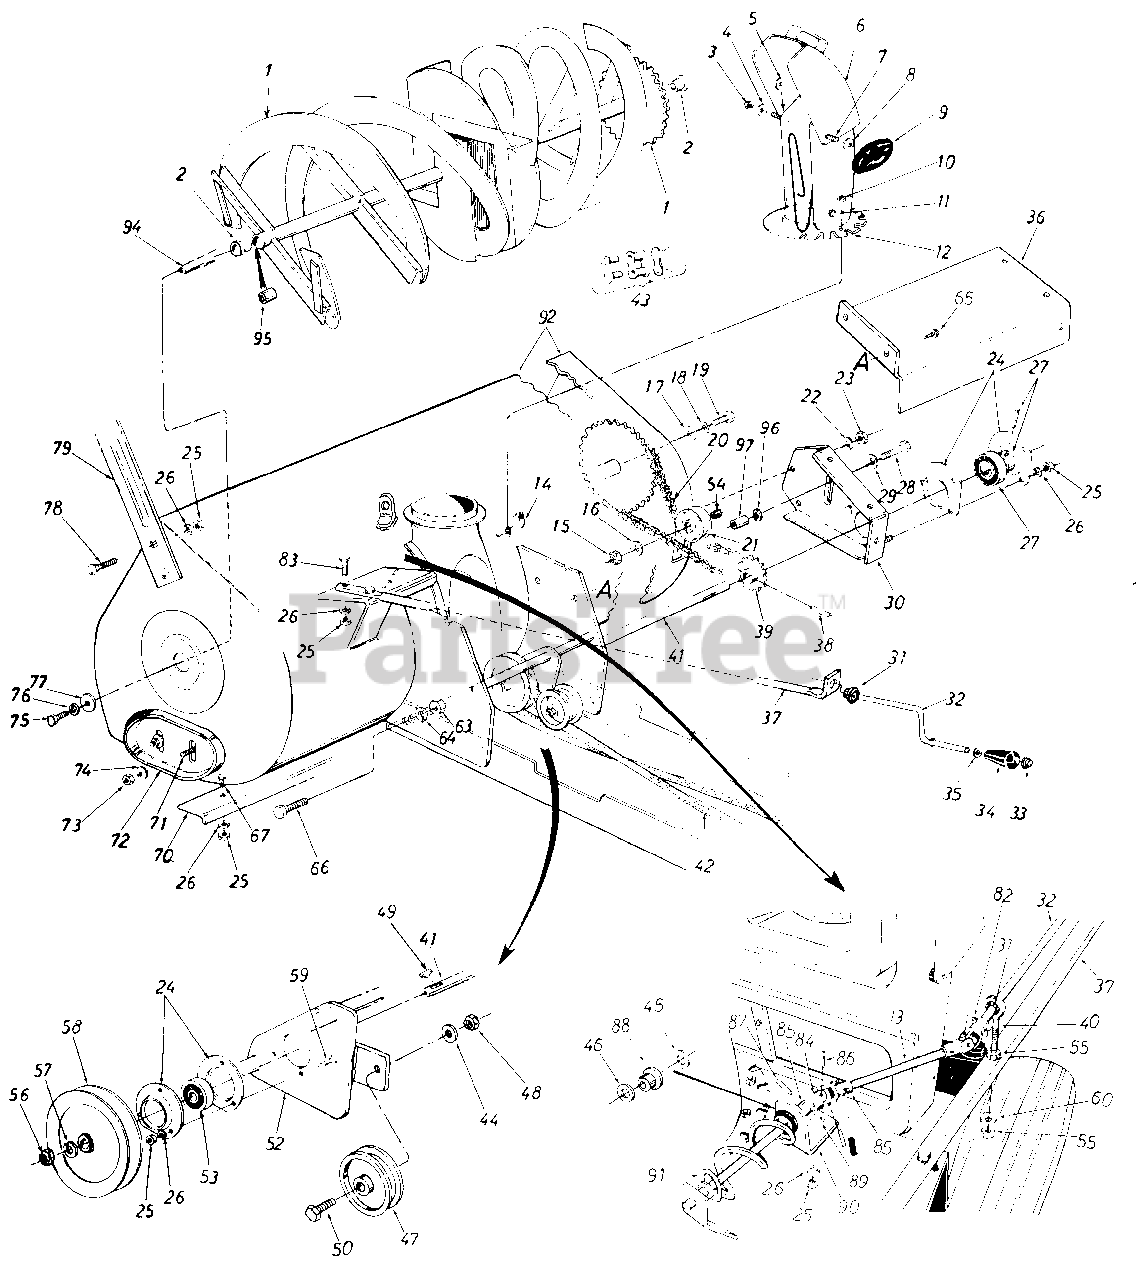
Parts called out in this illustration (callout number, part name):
1	Spiral Ass'y.
2	Flange Bearing
3	Hex Cent. L.-Nut 5/16-18 Thd.
4	Belleville Wash. 3/8" I.D.
5	Flat Washer 3/8" I.D.
6	Top Chute Ass'y.
7	Carriage Bolt 5/16-18 x .62" Lg.*
8	Belleville Wash. 3/8" I.D.
9	Hand Knob
10	Hex Cent. L.-Nut 1/4-20 Thd.
11	Push Cap .188" Dia. Rod
12	Chute Ass'y.
13	Chute Crank Extension Rod
14	Chute Flange Keeper Ass'y.
15	L.-Nut 3/8-16 Thd
16	FI .-Wash.
17	Fl.- Wash.
18	Belleville Wash.
19	Hex Bolt 1/2-13 x 1.00" Lg.*
20	#420 Chain 1/2" Pitch x 77 Links
21	Plastic Idler 2.00" O.D.
22	L.-Wash. 1/4" I.D.*
23	Hex Nut 1/4-20 Thd.*
24	Bearing Housing
25	Hex Nut 5/16-18 Thd.*
26	L.-Wash. 5/16" I.D.*
27	Self-Aligning Bearing
28	Hex Bolt 3/8-16 x 1.75" Lg. t
29	Belleville Wash. 3/8" I.D.
30	Chain Guard Ass'y.
31	Nylon Bushing
32	Chute Crank .375 Dia. x 33" Lg.
33	Push Nut 3/8" Rod
34	Knob 3/8" Dia. Hole
35	Flat Washer
36	Drive Shaft Cover
39	14 Teeth Sprocket Ass'y.
40	Eyebolt 5/16-18 x 3 .0 " Lg.
41	Drive Shaft
42	"V"-Belt 1/2" x 88" Lg. [ (Kevlar)
43	Master Link for #420 Chain
44	L.-Wash. 3/8" I.D.*
45	Fl.-Wash. .385 I.D. x .62" O.D.
46	Fl.-Wash. .390 I.D. x 1.50" O.D.
47	Fl.-Idler with Flanges
48	Hex Jam L.-Nut 3/8-26 Thd.
49	#61 Hi-Pro Key
50	Hex Bolt 3/8-16 x 1.50" Lg.*
52	Spiral Housing Ass'y.
53	Self-Aligning Bearing
54	Sleeve Bearing .50" I.D.
55	Hex Nut 5/16-18 Thd.*
56	Hex Nut 3/4-10 Thd.
57	L.-Wash. 3/4" I.D.
58	"V"-Pulley .750" I.D. x 6.00" O.D.
59	Hex Sems Bolt 5/16-18 x .75" Lg.*
60	Bell.-Wash. .345" I.D. x .88" O.D.
63	Hex L.-Nut 1/2-20 Thd.
64	L.-Wash. 1/2" I.D.*
65	Hex Wash. Hd. Tap Scr. 1/4-20 x.50" Lg.
66	Hex Bolt 1/2-20 x 1.25" Lg.*
67	Carriage Bolt 5/16-18 x .62"*
72	Skid Shoe
73	Hex Nut 3/8-16 Thd.*
74	BellevilleWash.3/8" I.D.
75	Hex Bolt 1/2-13 x 1.00" Lg.*
76	BelievilleWash. 1/2" I.D.
77	Fl.-Wash.
78	Carriage Bolt 5/16-18 x .62" Lg*
79	Drift Cutter
82	Cotter Pin
83	Hex Bolt 5/16-18 x 1.50" Lg.*
84	Joint Block
85	Joint Bracket Ass'y.
86	Spring Pin Roll 3/16" Dia. x .75" Lg.*
87	Spring Pin Roll 1/8" Dia. x .75 " Lg .*
88	Nylon Bushing
89	Carriage Bolt 5/16-18 x .62
90	Chute Crank Bracket
91	Chute Crank Ass'y.
92	Spiral Housing Ass'y.
95	Sleeve Bearing
96	Flat Washer
97	Idler Spacer
